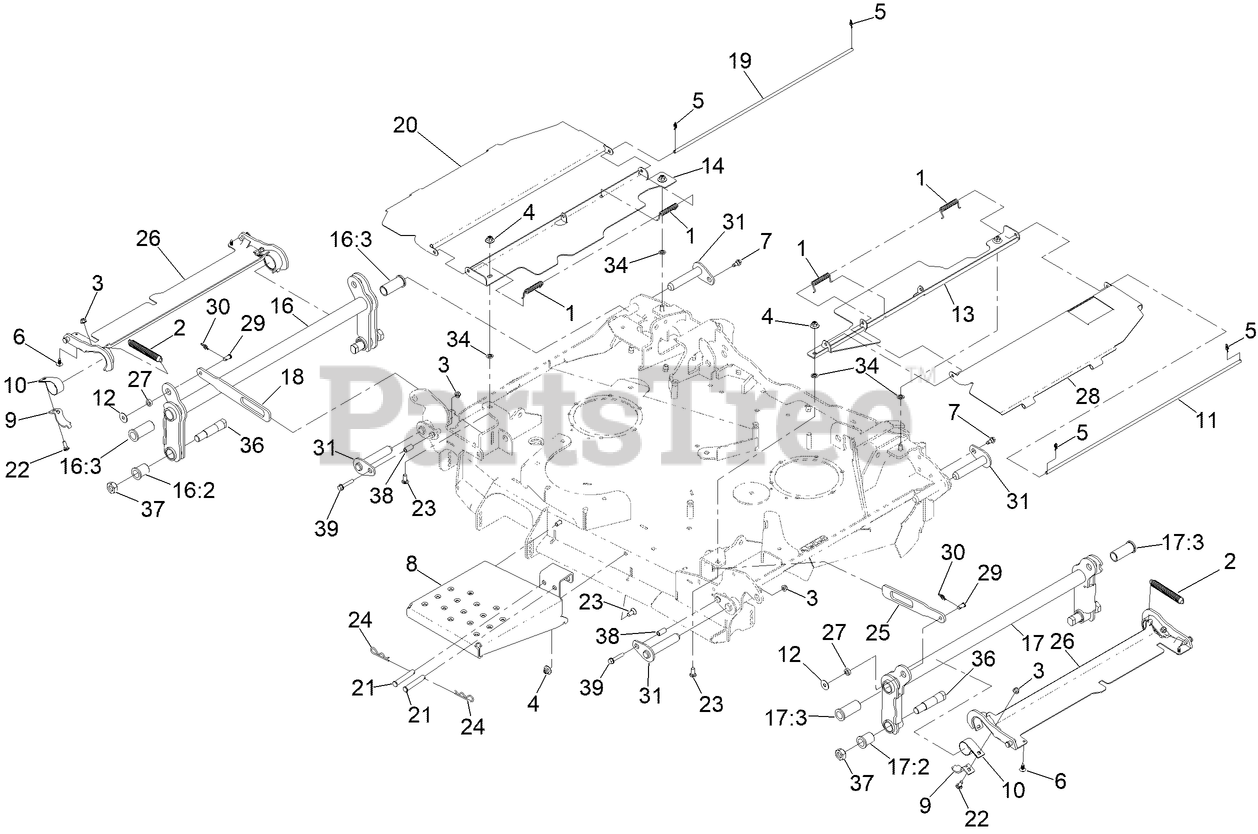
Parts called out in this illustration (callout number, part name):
1	SPRING-TORSION
2	SPRING
3	NUT-HF, NI
4	NUT-FLANGE, NI
5	PIN-COTTER, LOCKING
6	PLUG-PLASTIC
7	SCREW-SHOULDER
8	PLATE-DECK STEP
9	PLATE-RETAINER, BEARING
10	BEARING-STRAP, NYLON
11	COVER-ROD, PIVOT
12	WASHER
13	SHIELD-LH CENTER [RED]
14	SHIELD-CENTER, RH
16	ASM-RH FOLD ARM
16:2	BUSHING-FLANGED
16:3	BUSHING-FLANGE
17	ASM-LH FOLD ARM
17:2	BUSHING-FLANGED
17:3	BUSHING-FLANGE
18	STRAP-RH FLAG
19	ROD-CENTER COVER
20	PLATE-HINGED COVER
21	PIN-CLEVIS
22	SCREW-CARR
23	BOLT-CARR
24	PIN-HAIR
25	STRAP-LH FLAG
26	ASM-WING COVER, [RED]
27	BUSHING
28	COVER-HINGED, LH [BLACK]
29	PIN-CLEVIS
30	PIN-COTTER, LOCKING
31	ASM-DECK PIN
34	NUT-PUSH
36	BOLT-PIVOT PIN
37	NUT-LUG
38	TUBE-STANDOFF
39	SCREW-HWH
